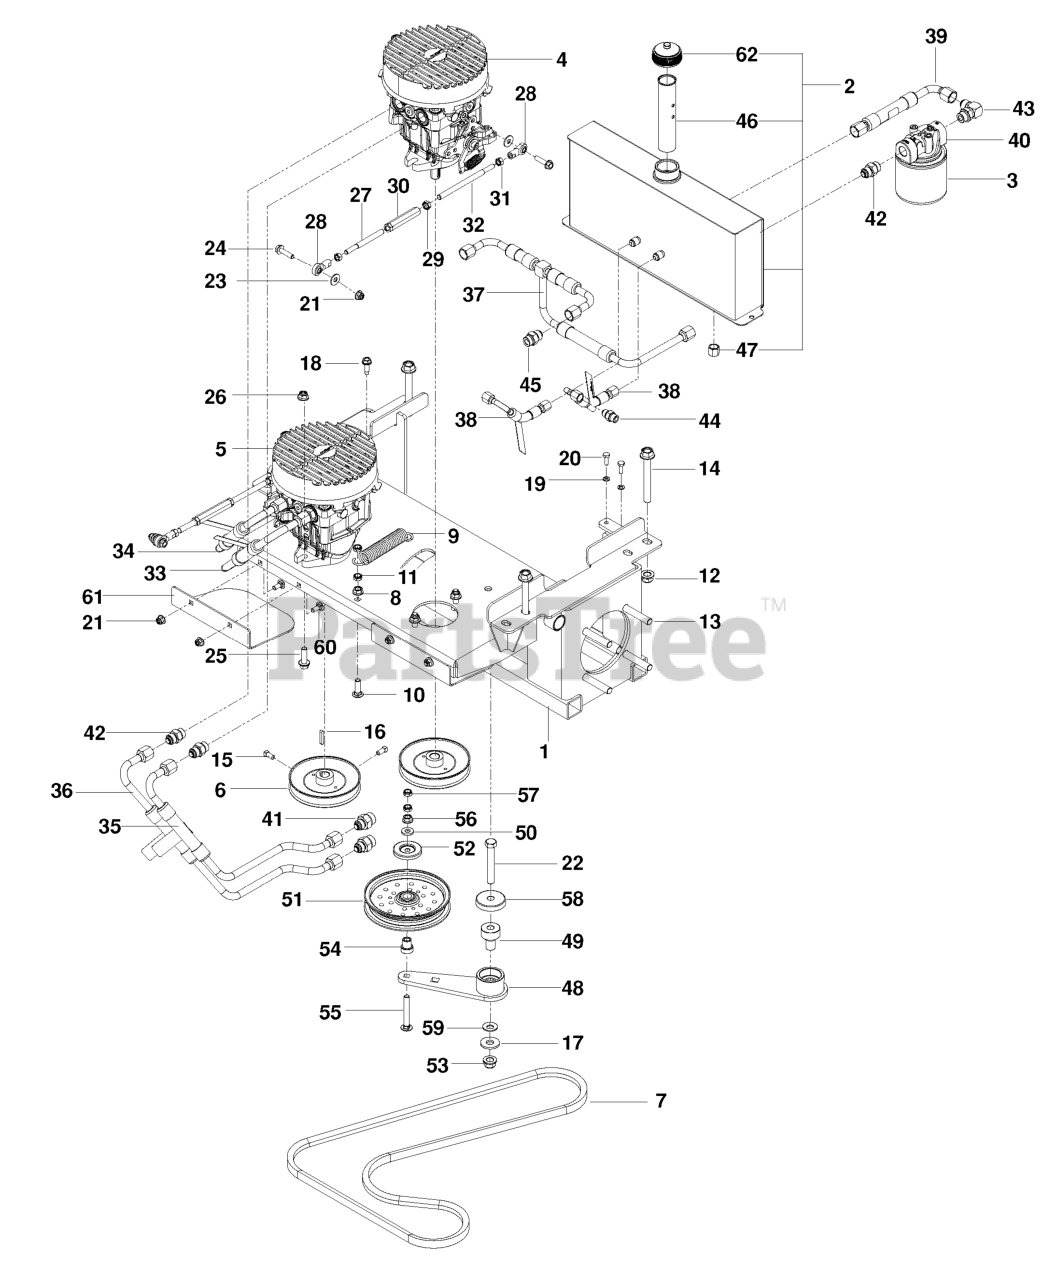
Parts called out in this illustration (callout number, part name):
1	FRAME, NYDR SUB, BLK
2	ASSEMBLY, OIL TANK
3	FILTER 25 MICRON
4	HG_PUMP, 12CC RT
5	HG_PUMP, 12CC LT
6	PULLEY, PUMP 15MM
7	BELT, "B", 75.5"
8	NUT 3/8C WHIZ
9	SPRING, PUMP
10	RHSNB 3/8-16 X 1-1/4
11	NUT HEX 3/8-16 NYLON, THIN
12	NUT, 1/2-13 HEX FLG NYLOC ZD
13	HCS 1/2C X 2 3/4
14	HHFS 1/2-13 X 4.0 GD8 ZD
15	SCREW 5/16C X 5/8 SQ HEAD
16	KEY 5 MM SQ X 25 MM
17	WASH USS FLAT 1/2
18	RP BLT 5/16-18 X 1 THRD FORM D
19	LOCKWASHER 1/4"
20	HCS 1/4C X 5/8
21	5/16-18 NYLOC FLANGE NUT
22	HCS 1/2C X 3 1/4
23	WASHER 5/16 FLAT
24	HHFS 5/16-18 X 1.25 TPBLT GD 5
25	HHFS 3/8-16 X 1.25 GD 5
26	NUT 3/8-16 HEX FLG NYLOC ZD
27	LINKAGE, CONTROL, FT
28	BALL JOINT, RIGHT HANDED
29	NUT 3/8-24 JAM
30	TURNBUCKLE, 3/8
32	LINKAGE, CONTROL, RR
33	LINE, RT A
34	LINE, RT B
35	LINE, LT A
36	LINE, LT B
37	LINE, CHARGE
38	LINE, CASE
39	LINE, SUCTION
40	FILTER HEAD
41	CONNECTOR, STRAIGHT
42	FITTING, STRAIGHT F6400-8-8-0
43	ELBOW, 90 DEGREE
44	STRAIGHT FITG
45	FITTING, HYDRO
46	TUBE, ANTI-SPLASH
47	NUT 9/16-18 JIC CAP
48	ARM, IDLER, STEEL, W/BGS
49	PIVOT, BEARING
50	WASHER, 3/8 THICK
51	IDLER, FLAT, 5.5"
52	DUST SHIELD
53	NUT, 1/2-13 HEX FLG NYLOC ZD
54	PIVOT, IDLER
55	RHSNB 3/8-16 X 2.75
56	NUT 3/8C WHIZ
57	NUT HEX 3/8-16 NYLON, THIN
58	SHIELD, DUST
59	CONTACT BELLSPR 1/2
60	BOLT 5/16C X 3/4" CARRIAGE
61	SHIELD, PULLEY, BLK
62	CAP, HYDRAULIC
